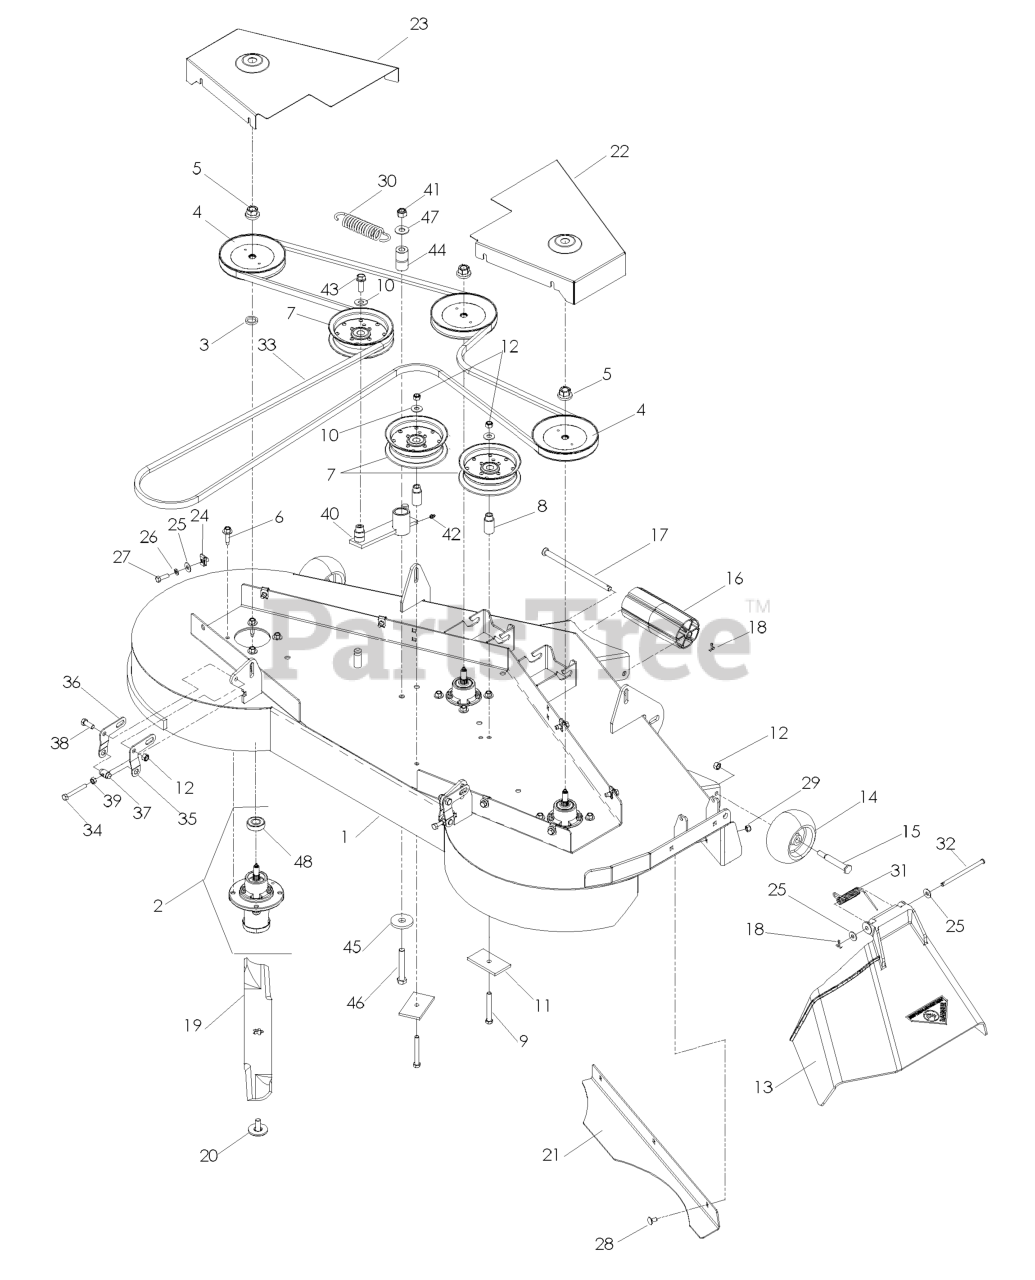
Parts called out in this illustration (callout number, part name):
1	DECK.SVC.W/DECALS.61".EZ.ORANG
2	MANDREL.DECK.ASSEMBLY
3	WASHER-SPACER
5	LOCKNUT - 9/16
6	WASHER HEAD SCREW
7	PULLEY, IDLER
8	IDLER BUSHING
9	HCS 3/8C X 3
10	WASHER 3/8 FLAT
11	SUPPORT PLATE
12	NUT 3/8-16 NYLOC
13	DISCHARGE CHUTE 61"
14	GAUGE WHEEL
15	SHOULDER BOLT 1/2X2-5/8 ZD SPE
16	NOSE ROLLER 48"
17	NOSE ROLLER ROD
18	RP_COTTER PIN 1/8 X 3/4
19	BLADE, 21"
20	BLADE BOLT ASSY-7/16" TB REPL
21	CONFINEMENT PLATE 61
22	BELT SHIELD, RH ORANGE
23	BELT.SHIELD.LH.ORANGE
24	U-CLIP 5/16-18 NUT RETAINER
25	WASHER 5/16 FLAT
26	WASHER.LOCK.HVY.HLCL.SPR.5/16
27	HCS 5/16C X 1
28	CARRIAGE BOLT 5/16C X 5/8"
29	NUT 5/16 NYLOC
31	SPRING - TORSION
32	PIN-CLEVIS 5/16 DIA X 5.19 ZD
33	BELT, DECK
34	HCS 5/16-18 X 2 1/2 TPBLT
35	PITCH, ADJUST, RT
36	PITCH, ADJUST, LT
37	TRUNION, PITCH
38	HCS 3/8-16X1.GRD.5.ZD
39	NUT 5/16C HEX
41	NUT 1/2-13 HEX NYLOC ZD
42	ZERK
43	4CS 3/8C X 1 SERRATED HEAD
44	PIVOT BUSHING
45	WASHER, SUPPORT
46	HCS 1/2C X 3 1/4
47	WASHER 1/2 FLAT
48	BAFFLE LEFT 54
